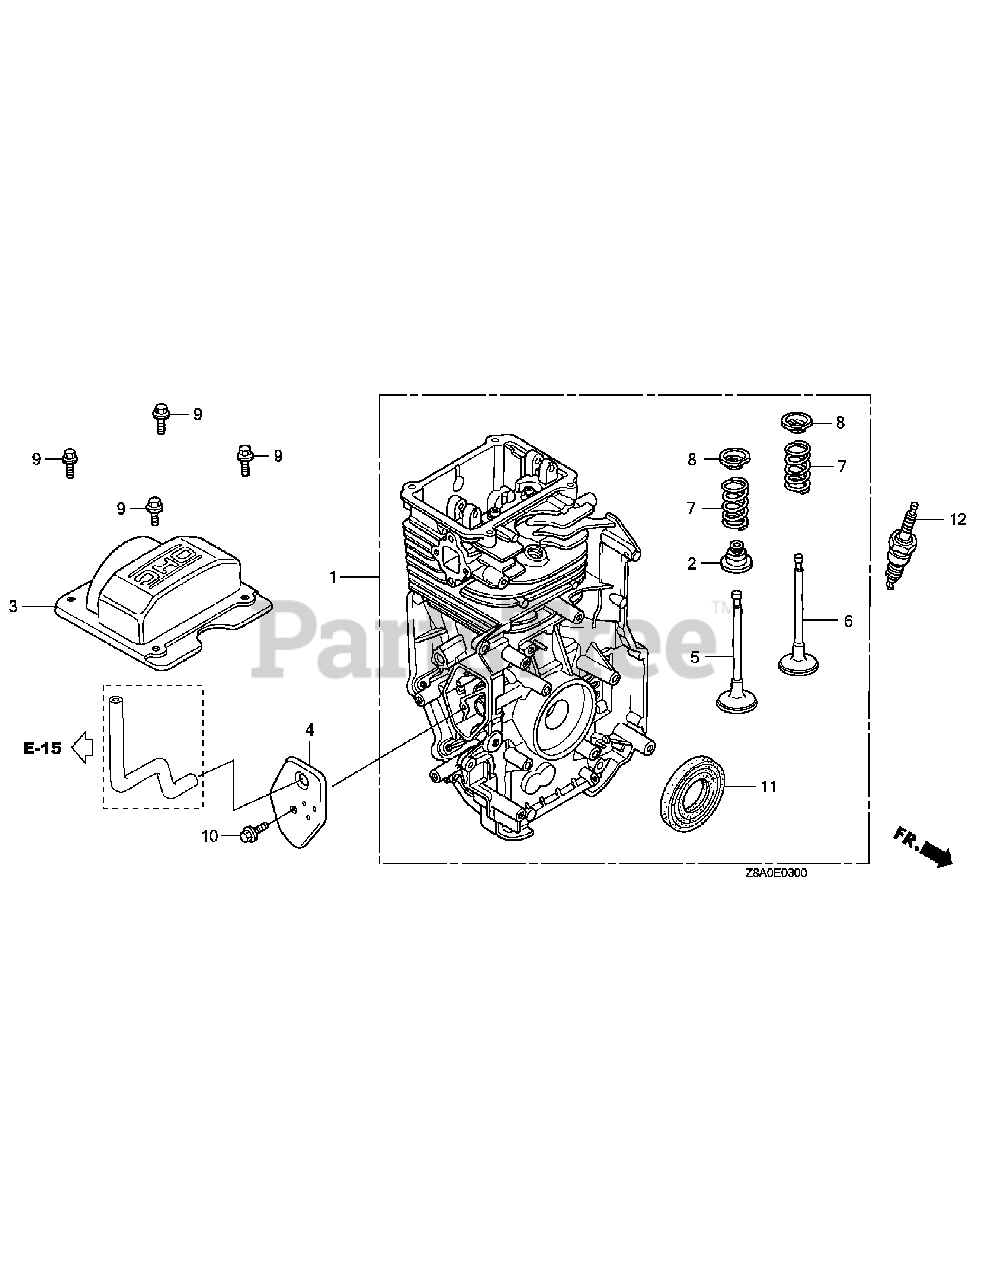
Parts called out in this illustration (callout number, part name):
1	Barrel Assembly, Cylinder
2	Seal, Valve Stem
3	Cover Complete, Cylinder Head
4	Cover Complete, Breather
5	Valve, Inlet
6	Valve, Exhaust
7	Spring, Valve
8	Retainer, Valve Spring
9	Bolt, Flange, 6 x 12 (CT200)
10	Bolt, Flange, 6 x 14 (CT200)
11	Oil Seal, 25.4 x 62 x 6
12	Plug Spark (BPR6ES) (NGK)
